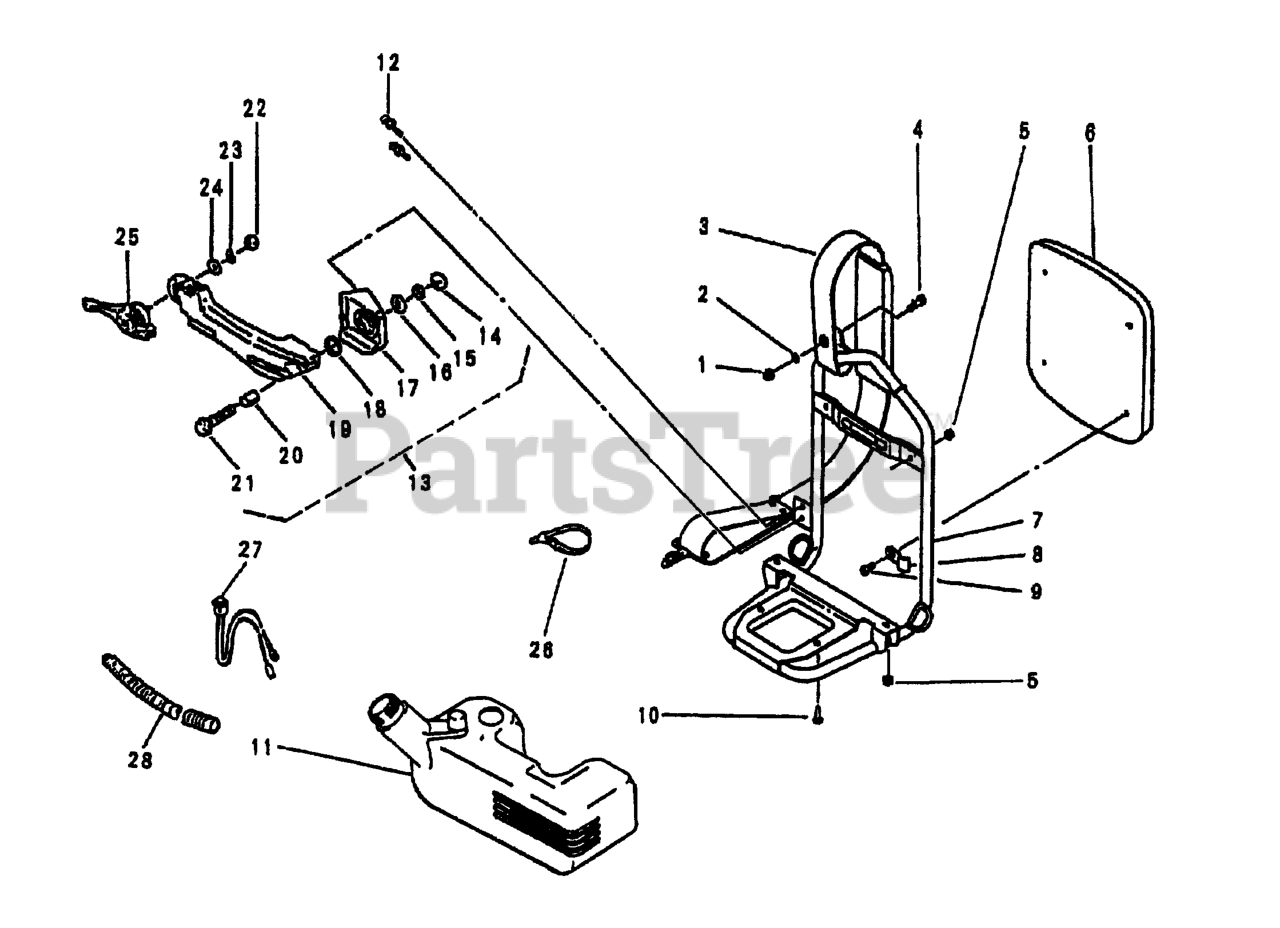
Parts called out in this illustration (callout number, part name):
1	NUT
2	WASHER
3	Shoulder Band
4	TRUSS SCREW
5	Flange Nut
6	KNAPSACK PAD
7	Backpack Frame
8	PAD FITTING
10	SCREW 6X10MM 374L0610
12	Screw (M5x12)
13	LEVER C.P.
14	HEXAG0N NUT 5MM
15	SPRING LOCK WASHER 8MM 661L080
16	PLAIN WASHER 8MM 612L0800
17	STAY 11113-238
18	O-RING 211B2100
21	FLANGE BOLT 8X2.5MM
22	HEXAG0N NUT 5MM
23	SPRING LOCK WASHER 5MM
24	PLAIN WASHER 5MM 613L0500
25	THROTTLE LEVER
26	WIRE BAND
27	SWITCH STOP
28	TUBE 41003-137
